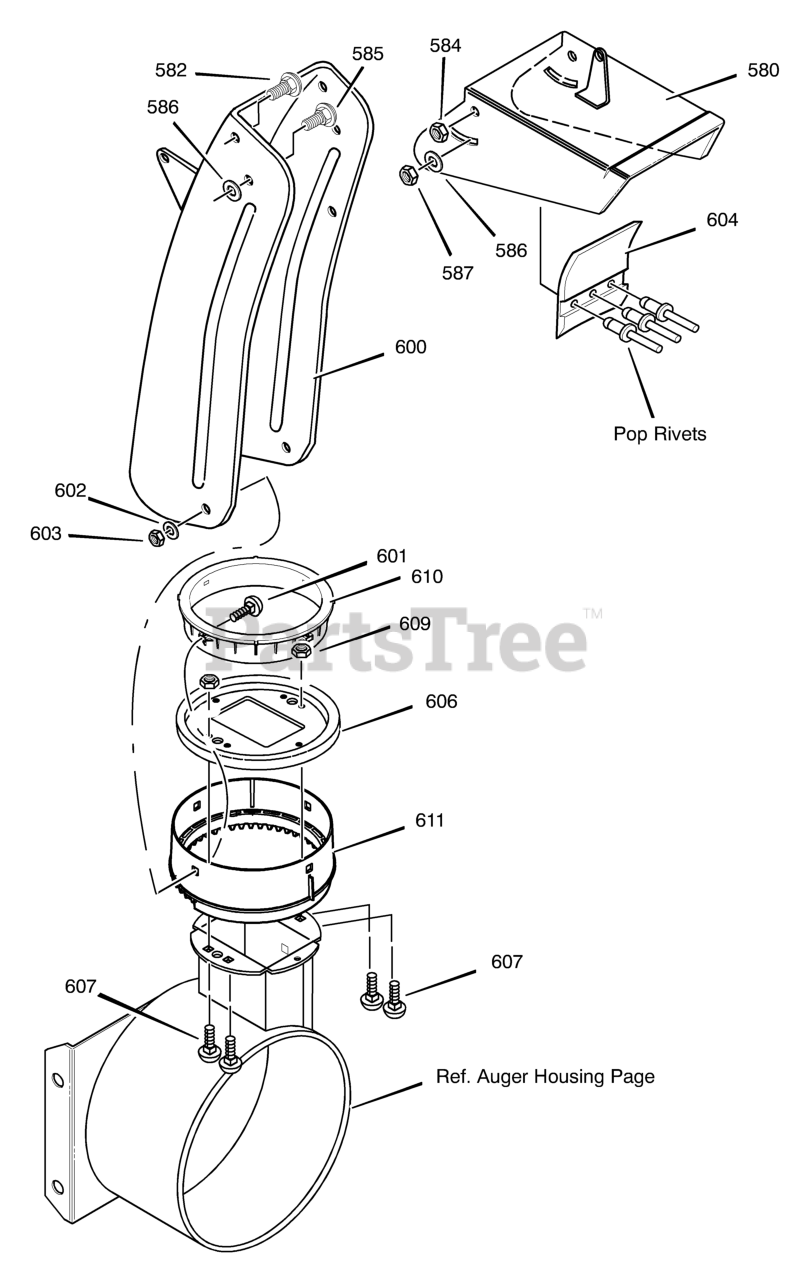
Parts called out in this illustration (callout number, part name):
580	CHUTE, UPPER W/REMOTE
582	SCREW, 5/16-18 x 0.75
584	NUT
585	SCREW, 5/16-18 x 0.75
586	PLASTIC WASHER
587	NUT
600	CHUTE, LOWER W/REMOTE
602	WASHER, FLAT
603	NUT
606	CHUTE COLLAR
607	BOLT
609	NUT
610	RETAINER, RING INNER
611	RETAINER, RING OUTER
